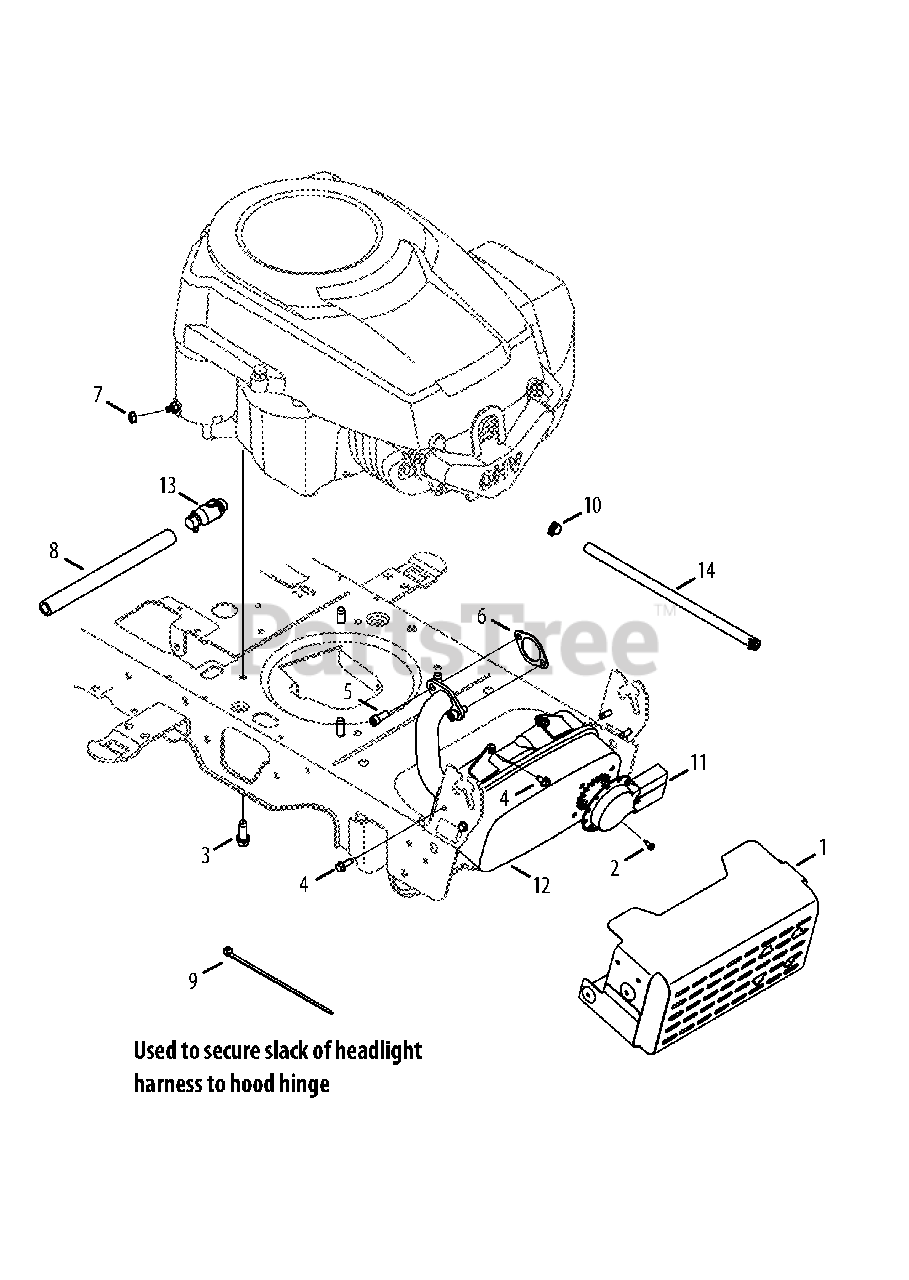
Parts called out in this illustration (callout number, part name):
1	Muffler Shield Assembly
2	Screw, Indented Washer, #8-18:0.500
3	Taptite Screw, 3/8-16:1.000
4	Taptite Screw, 1/4-20:0.750, Briggs
5	Socket Head Screw, 5/16-18:.750
6	Gasket, Exhaust, Briggs
7	Sems Nut, 1/4-20
8	Extension Hose, Oil Drain
9	Cable Tie, 3/16 x .05 x 7.4
10	Hose Clamp, .490 DIA.
11	Long Muffler Deflector
12	Muffler, Briggs
